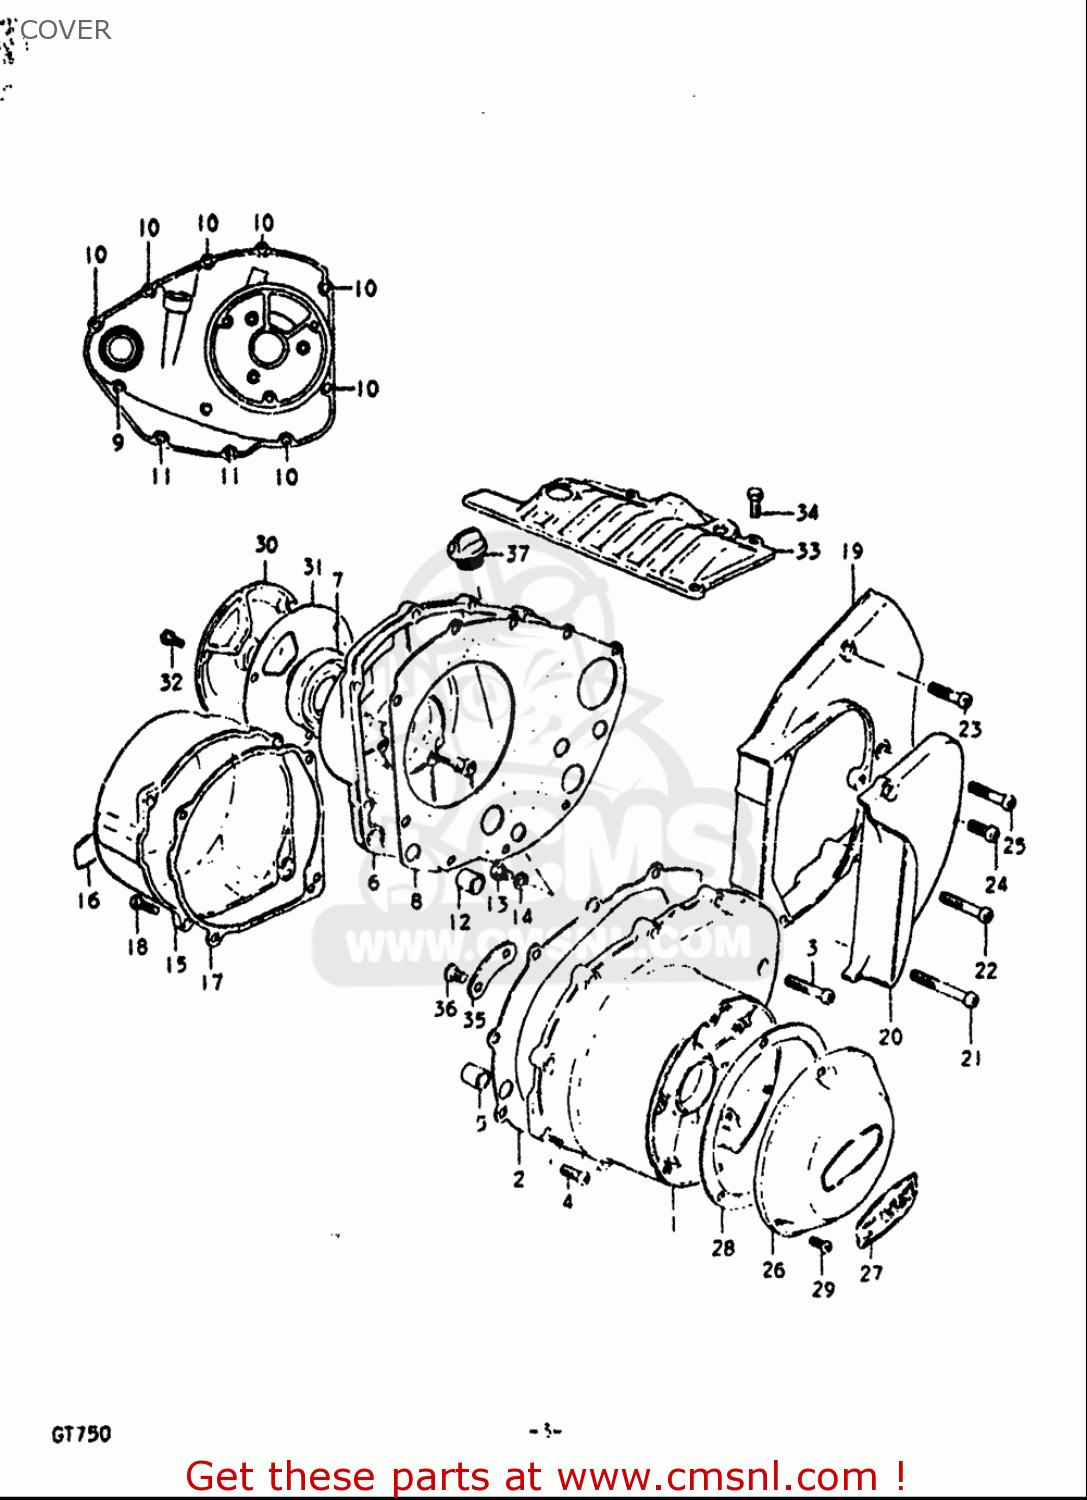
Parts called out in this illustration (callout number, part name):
2	GASKET GEAR COVER (NAS)
3	SCREW
4	SCREW
5	PIN
7	SEAL,OIL(25X34X6)
8	GASKET,CLUTCH COVER (NAS)
9	SCREW
10	SCREW
11	SCREW
12	PIN
13	SCREW(6X10)
14	GASKET(6.2X11X1) (NAS)
15	COVER,GENERATOR
16	EMBLEM,GENERATOR COVER
17	GASKET,GENERATOR COVER (NAS)
18	SCREW
21	SCREW
22	SCREW
23	SCREW
24	SCREW
25	SCREW
26	CAP SET,CONTACT BREAKER
27	EMBLEM,GENERATOR COVER
28	GASKET,CONTACT BREAKER CAP (NAS)
29	SCREW
31	GASKET,CL RLSE ADJ CAP (NAS)
32	SCREW
34	BOLT
36	SCREW
37	PLUG SET
